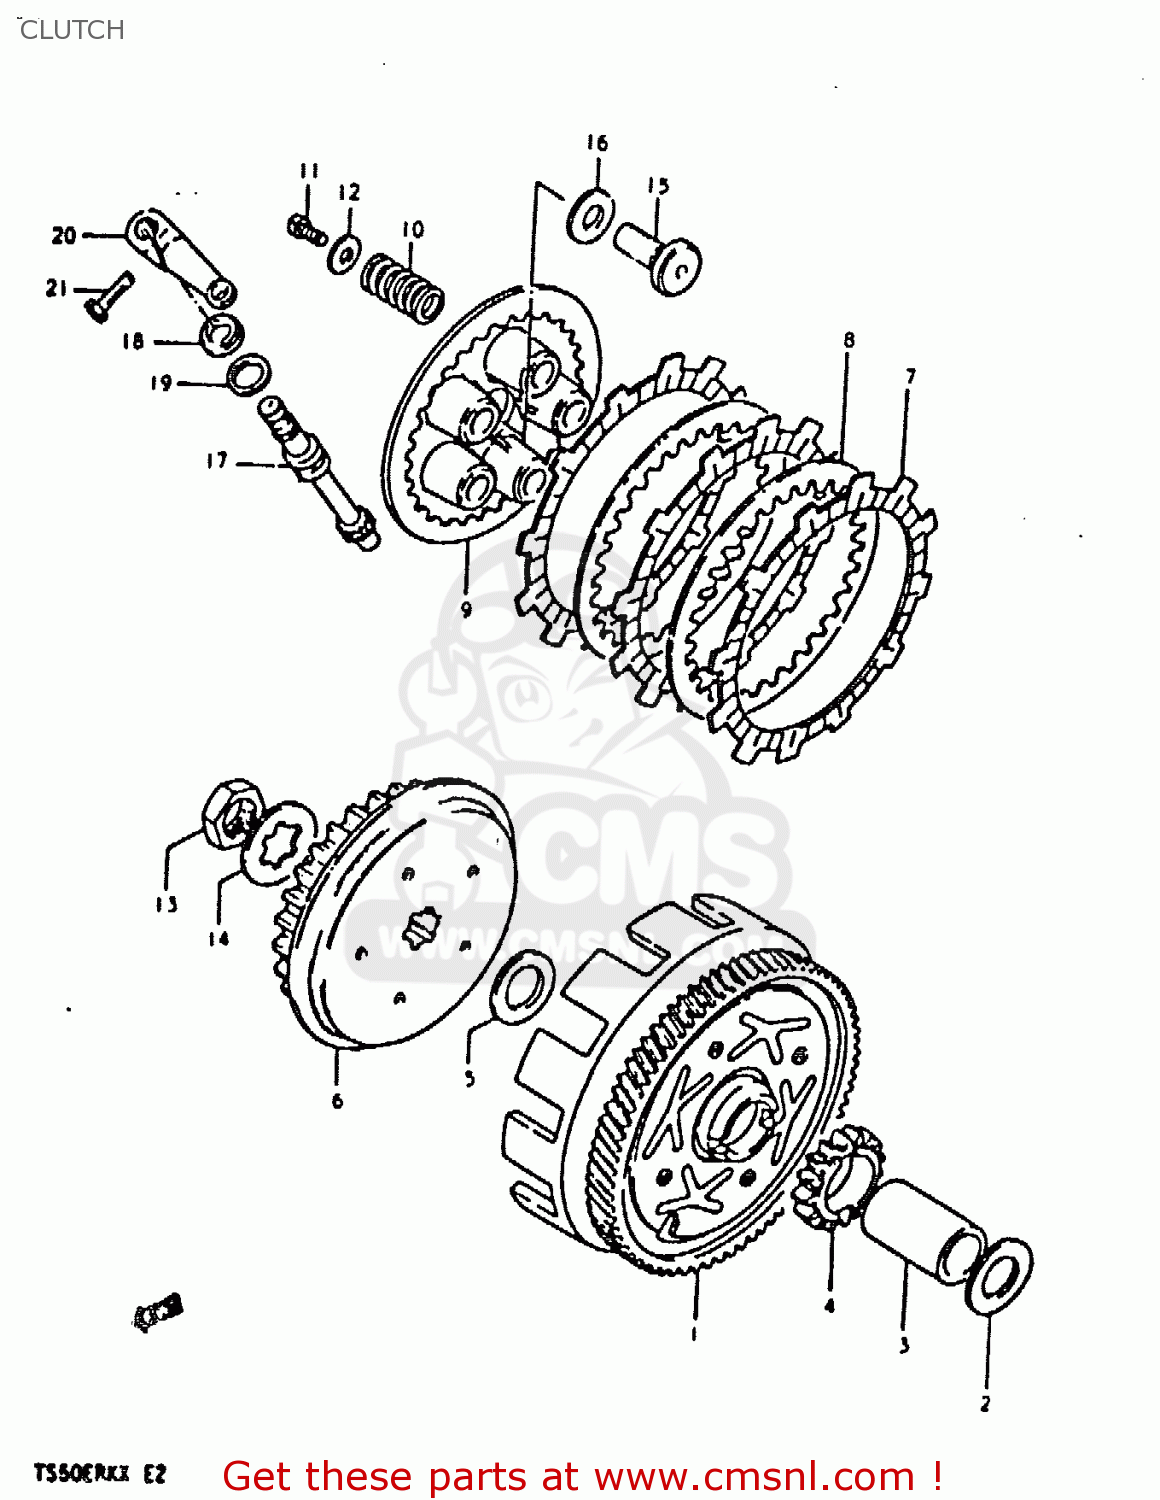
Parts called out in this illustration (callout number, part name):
1	GEAR ASSEMBLY,PRIMARY DRIVE
2	WASHER,THRUST
3	SPACER
4	GEAR,KICK STARTER DRIVE
5	WASHER
6	HUB,CLUTCH SLEEVE
7	PLATE,CLUTCH DRIVE
8	PLATE,CLUTCH DRIVEN (NAS)
9	DISC,CLUTCH PRESSURE
10	SPRING
11	BOLT(5X16)
12	WASHER (5.5X16X1.2)
13	NUT
14	WASHER,LOCK
15	RACK,CLUTCH RELEASE
16	BEARING(10X22X2.8)
17	PINION,CLUTCH RELEASE
18	OIL SEAL
19	WASHER (12X17X1)
20	ARM,CLUTCH RELEASE
21	BOLT, UPPER
